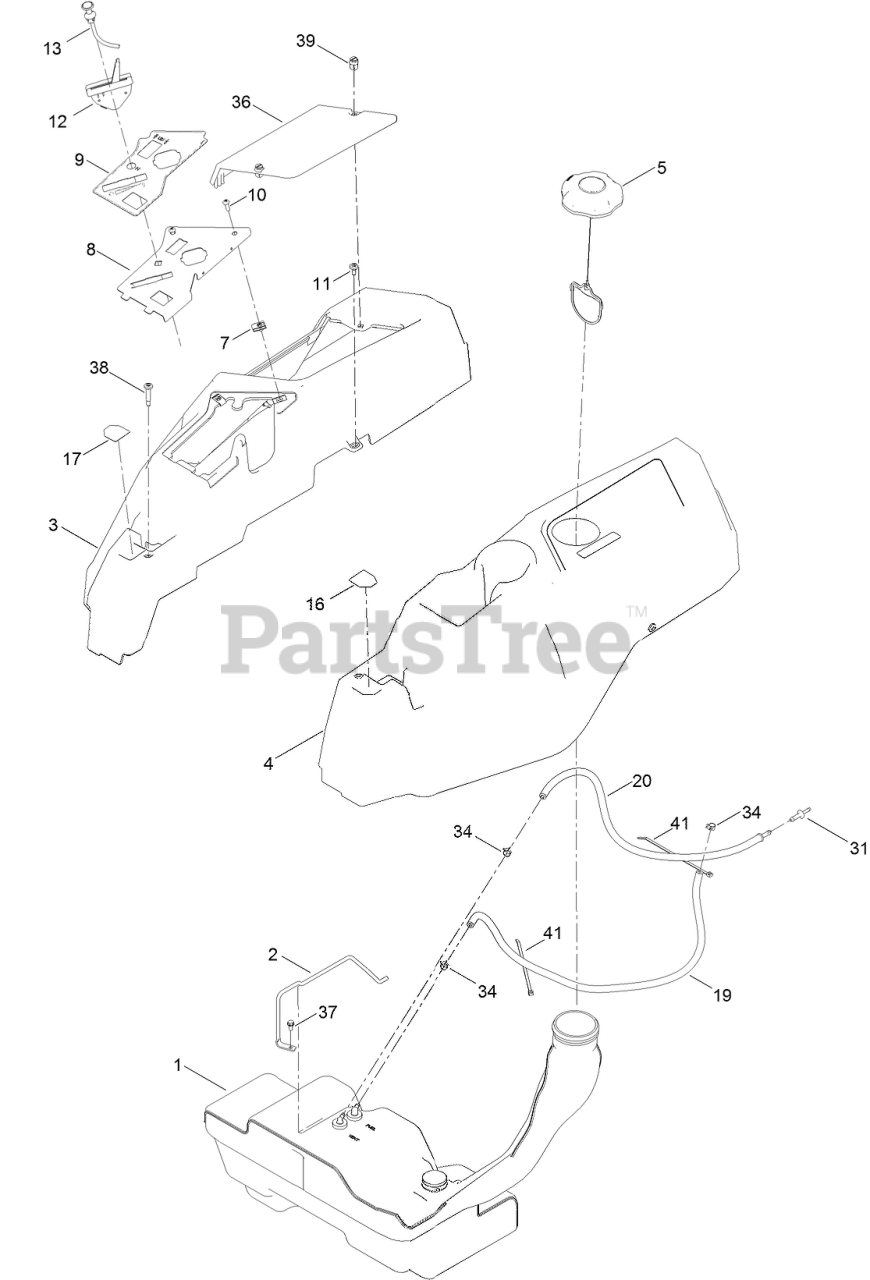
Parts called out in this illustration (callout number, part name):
1	FUEL TANK ASM
2	ROD-HOLD DOWN
3	POD-RH
4	POD-LH
5	CAP-FUEL, RATCHETING
8	PANEL-CONTROL
9	DECAL-PANEL, CONTROL
10	SCREW-PRH
11	SCREW-SHOULDER
12	CABLE-THROTTLE
13	CABLE-CHOKE
16	DECAL-LEVER, CONTROL (LH)
17	DECAL-LEVER, CONTROL (RH)
19	HOSE-FUEL
20	HOSE-FUEL
31	ADAPTOR-ORIFICE
34	CLAMP-HOSE
36	COVER-BATTERY
37	SCREW-HWH
38	SCREW-SHOULDER
39	FASTENER
41	TIE-CABLE
